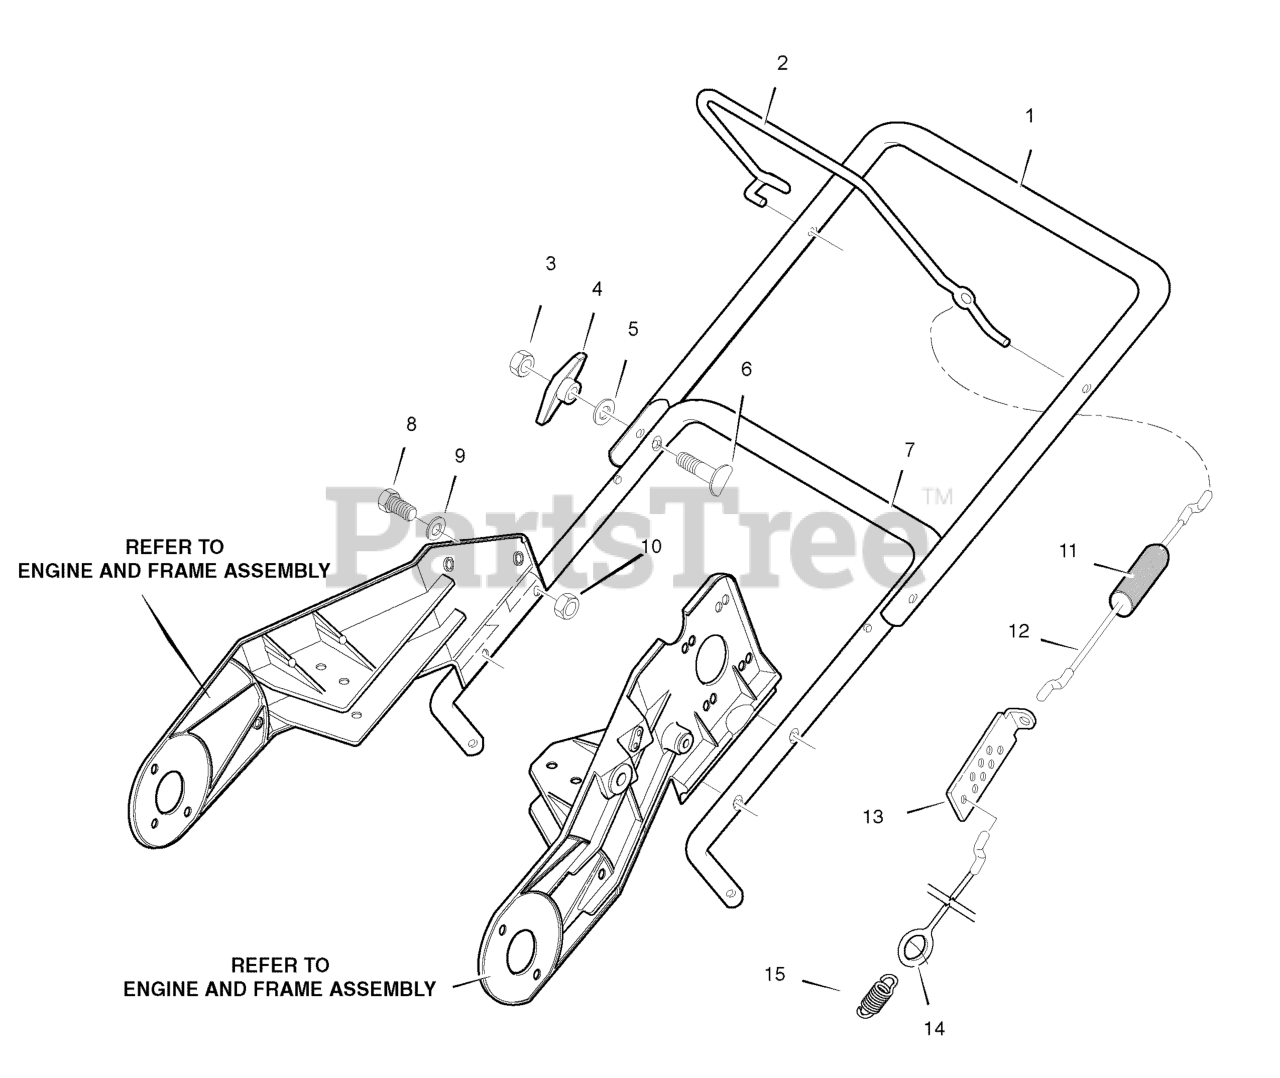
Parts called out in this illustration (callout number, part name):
1	HANDLE, UPPER
2	BAIL, CONTROL
3	NUT, 5/16-18 HEX
4	KNOB, WING
5	WASHER, FORM
6	BOLT, 5/16-18 X 2.00
7	HANDLE, LOWER
8	SCREW, 1/4-20 X 1.25
9	WASHER, FLAT
10	NUT, 1/4-20 HEX
11	BOOT, CLUTCH SPRING
12	CABLE, UPPER CONTROL
13	BRACKET, CABLE ADJUST
14	CABLE, LOWER CONTROL
15	SPRING, EXTENSION
